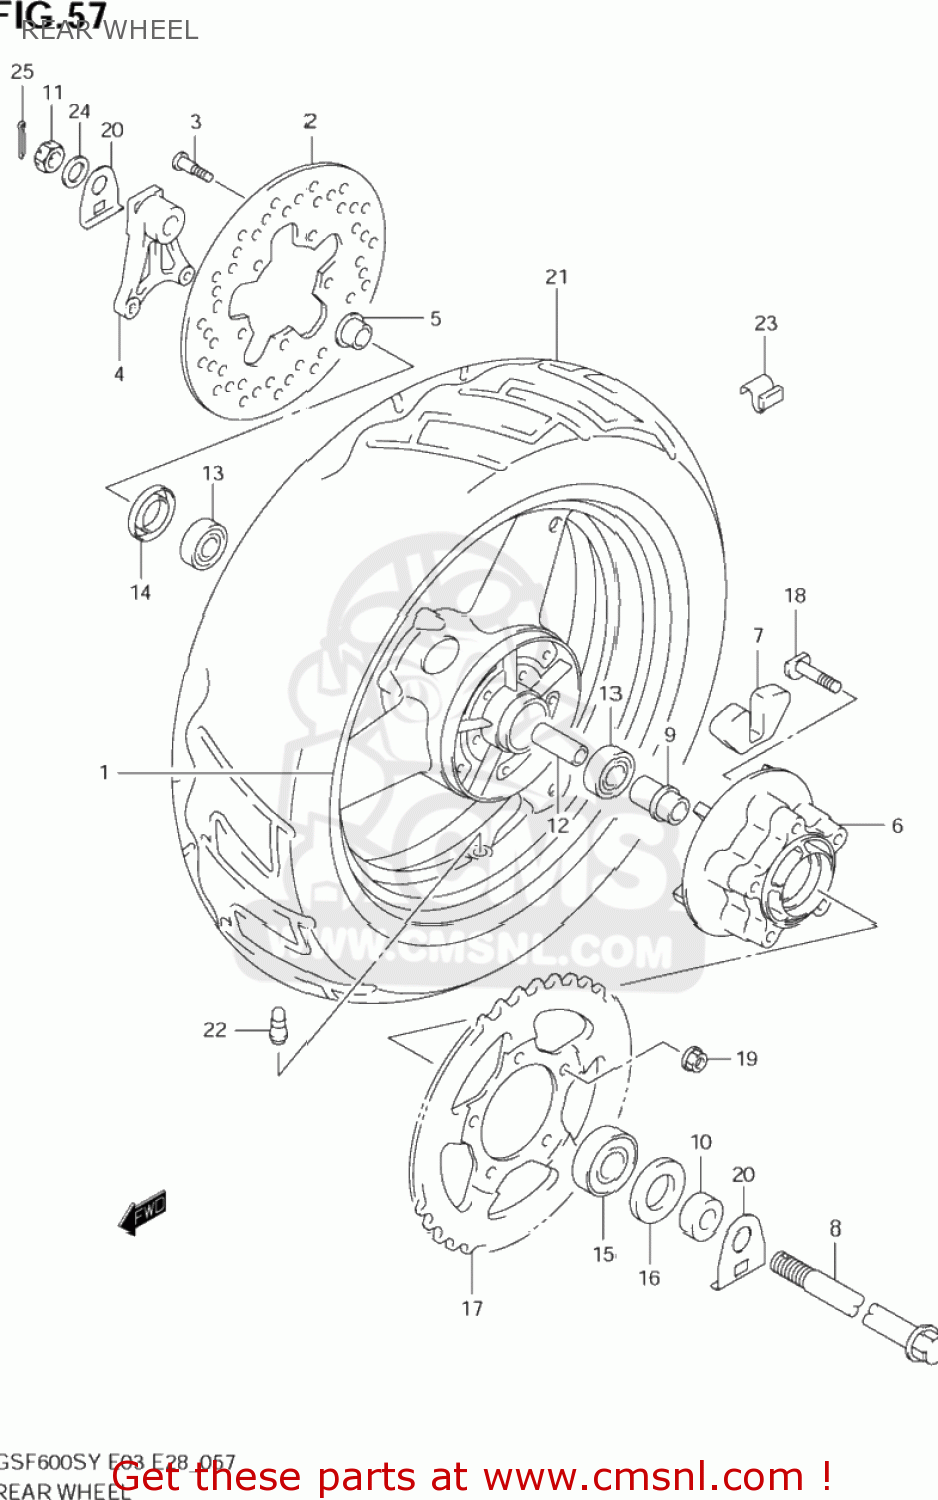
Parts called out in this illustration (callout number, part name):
1	WHEEL,REAR,17X
2	DISC,RR BRAKE
3	BOLT 8X33
4	BRACKET,RR CALIPER
5	SPACER,RR AXLE,R
6	DRUM,RR SPROCKET
7	ABSORBER,RR HUB SHOCK
8	AXLE,RR
9	RETAINER,RR HUB BEARING
10	SPACER,RR AXLE,L
11	NUT
12	SPACER(20.5X28X88)
13	BEARING(20X47X14)
14	SEAL,OIL(28X47X7)
15	BEARING(25X62X17)
16	SEAL,OIL(35X62X8)
17	SPROCKET,RR(NT:47-530)
18	BOLT(10X47)
19	NUT
20	WASHER,CHAIN ADJUSTER
21	TIRE,RR(160/60 ZR17 69W)
22	VALVE ASSY,WHEEL RIM(TR412)
23	BALANCER,WHEEL (10G)
24	WASHER(18.5X28X2.6)
25	PIN, COTTER
